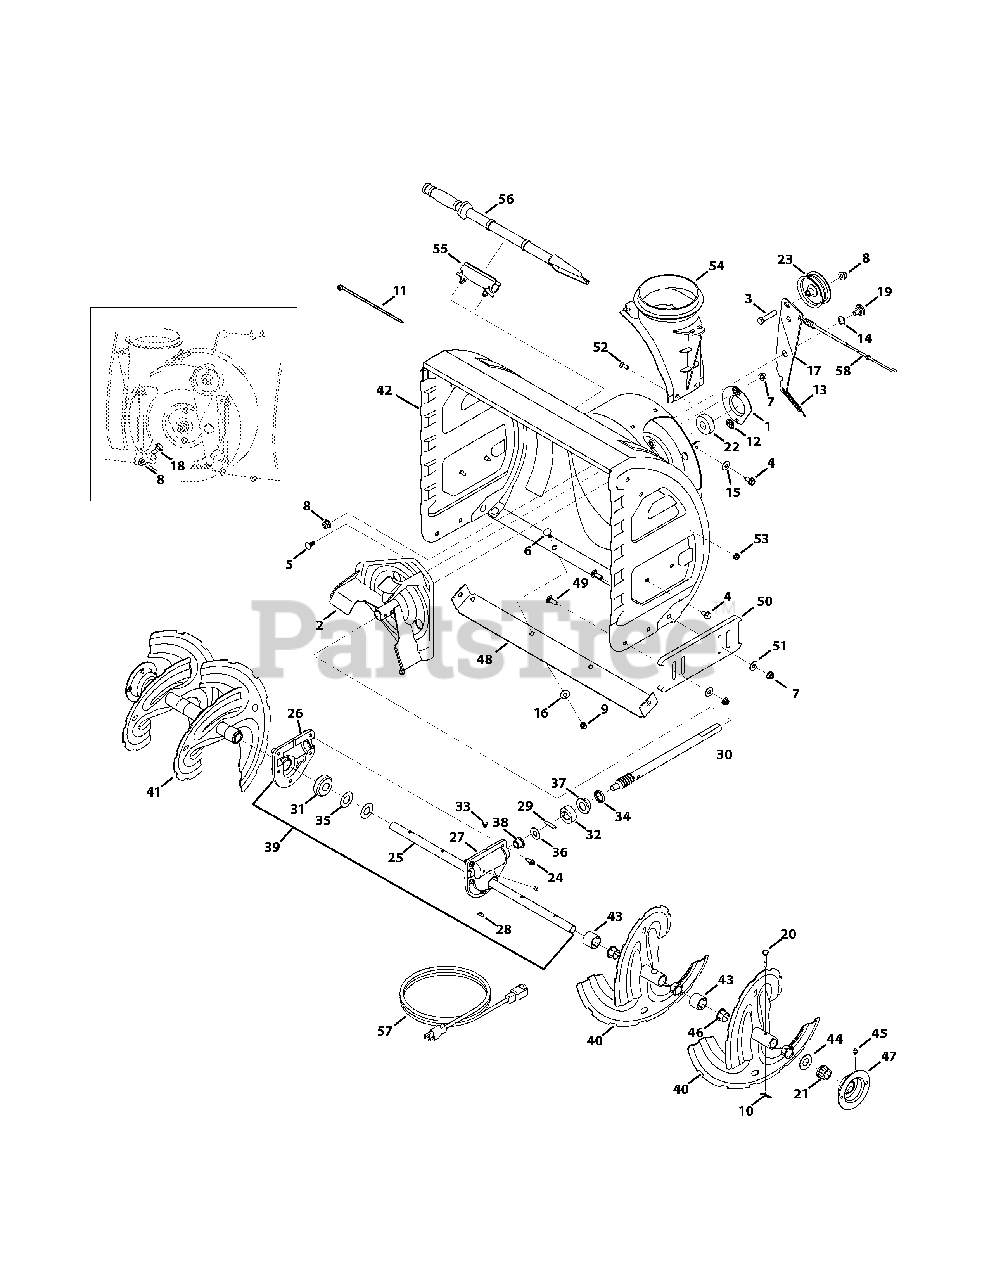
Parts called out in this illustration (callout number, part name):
1	Bearing Housing, 1.85 ID
2	Impeller Assembly, 12" Dia.
3	Hex Screw, 3/8-16 x 1.75
4	Taptite Screw, 5/16-18 x .750
5	Carriage Bolt, 5/16-18 x .75, Grade 5
6	Carriage Bolt, 5/16-18 x .750, Steel
7	Flange Lock Nut, 5/16-18
8	Flange Lock Nut, 3/8-16
9	Hex Nut, 5/16-18
10	Bow-Tie Cotter Pin
11	Cable Tie
12	Push-On Nut, .25 Dia.
13	Extension Spring, .38 OD x 4.59
14	Wave Washer, .625 x .885 x .0175
15	Washer, Bell, .340 x .872 x .060
16	Bell Washer, .340 x .872 x .06, Steel
17	Auger Idler Bracket
18	Shoulder Bolt, 3/8-16 x .496 x .336
19	Shoulder Screw, 3/8-16 x .625 x .17
20	Shear Pin, .25 x 1.50
21	Hex Flange Bearing x .75 ID
22	Flange Ball Bearing, .75 ID x 1.85 OD
23	Flat Pulley, 2.75 OD
24	Taptite Screw, 1/4-20 x .750
25	Auger Axle
26	Housing Assembly, RH
27	Housing Assembly, LH
28	Hi-Pro Key, 3/16 x 5/8
29	Dowel Pin, .25OD x 1.25
30	Worm Shaft, .75 OD
31	Worm Gear, 20T
32	Thrust Collar, .756 ID x .600
33	Plug, 1/4 x .437
34	Oil Seal, .75 x 1.131 x .188
35	Flat Washer, .760 ID x 1.50 OD
36	Flat Washer, .51 x 1.12 x .06
37	Flange Bearing, .75 ID x 1.0 OD x .59
38	Flange Bearing, .50 ID x .75 OD x .59
39	Gear Box; includes Ref. 24 - 38
40	Spiral Assembly (Left)
41	Spiral Assembly (Right)
42	Auger Housing, 24"
43	Spacer, 1.25OD x .75ID x 1.00
44	Flat washer, .76 x 1.49 x .06
45	Drive Lube Fitting, 3/16
46	Flange Bushing, .800 ID x .910 OD
47	Bearing Housing
48	Shave Plate, 24"
49	Screw, Carriage, 5/16-18 x 1.00
50	Deluxe Shoe
51	Washer, Flat, .349 x .879 x .063
52	Carriage Screw, 1/4-20 x .75
53	Flange Lock Nut, 1/4-20
54	Chute Adaptor, 5" Dia.
55	Cleanout Tool Mount
56	Cleanout Tool
57	Extension Cord
58	Auger Drive Cable
